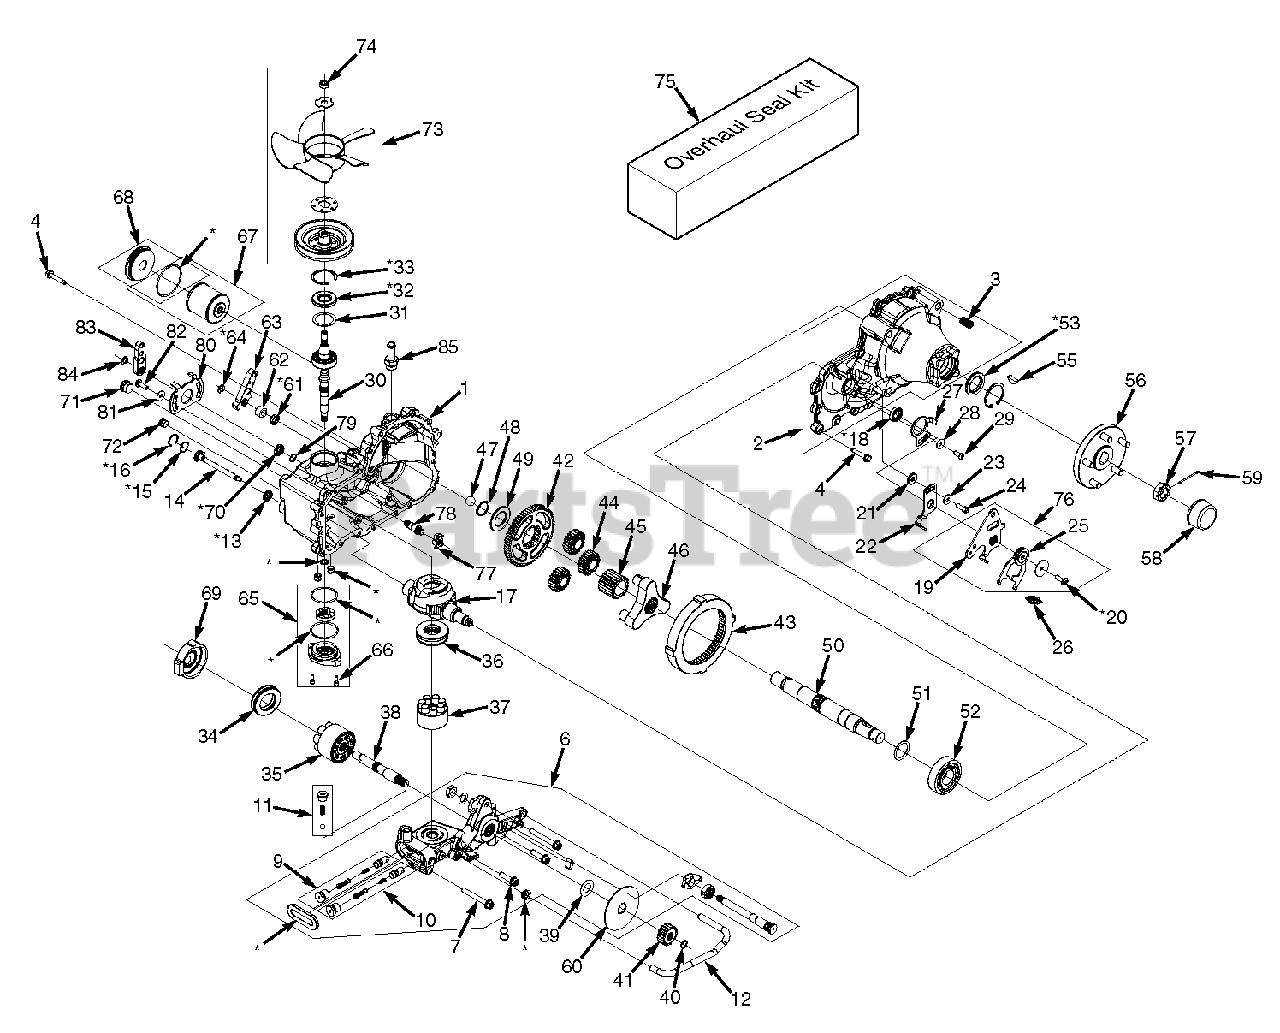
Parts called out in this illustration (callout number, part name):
1	Kit, Housing Main, LH
1	Kit, Housing Main, RH
2	Kit, Housing Side, LH
2	Kit, Housing Side, RH
3	Insert, 1/2-13 x 1-1/2" UNC
4	Screw, Hex Flange 5/16-18 x 1-1/2"
5	Tube, Sealant
6	Kit, Center Section, LH
6	Kit, Center Section, RH
7	Bolt, Hex Flange 3/8-16 x 3"
8	Screw, Hex Flange Head 3/8-16 x 1-1/2"
9	Kit, Shock Valve
10	Kit, Shock Valve
11	Kit, Charge Relief
12	Tube, Filter, LH
12	Tube, Filter, RH
13	Seal, Lip 12x 24 x 5 TC
14	Kit, Bypass Actuator
15	Spring, Wave
16	Ring, Retaining, HO-100
17	Swash Plate, 16cc. Machined
18	Seal, Lip 22 x 32 x 7
19	Arm, Control, LH
19	Arm, Control, RH
20	TWHCS, 5/16-18 x 1" (Patch)
21	Spacer, .320 x 1.005 x .179
22	Arm, Neutral, LH
22	Arm, Neutral, RH
23	Washer, .34 x .88 x .06
24	SHCS, 5/16-24 x .875 (Patch)
25	Assembly, RTN Uni-Directional (CCW) LH
25	Assembly, RTN Uni-Directional (CW) RH
26	Spring, Extension, RTN - 44lbs
27	Plate, Stop, LH
27	Plate, Stop, RH
28	Washer, .34 x .88 x .06
29	HBHCS, 5/16-18 x 3/4"
30	Kit, Input Shaft
31	Spacer
32	Seal, Lip 25 x 52 x 7 TC
33	Ring, Retaining Internal
34	Bearing, Thrust 42 x 68 x 16
35	Kit, Cylinder Block - 21cc.
36	Bearing, Thrust 35 x 70 x 22
37	Kit, Cylinder Block - 16cc.
38	Shaft, Motor
39	Washer, .89 x 1.50 x .04
40	Ring, Retaining
41	Gear, 19T
42	Gear, 65T
43	Gear, Ring 68T
44	Gear, Planet 23T
45	Gear, Sun 22T
46	Carrier
47	Ball, Thrust .75
48	Ring, Retaining 1-1/4"
49	Spacer, Thrust, Axle
50	Shaft, Axle
51	Washer, 1.40 x 1.75 x .05
52	Bearing, Ball 35 x 80 x 21
53	Seal, Lip 1.375 x 2.062 x .250
54	Ring, Retaining Internal
55	Key, Shaft, Axle
56	Kit, Hub, 5-Bolt
57	Nut, Hex 1-20 Slotted
58	Cap, Axle
59	Pin, Cotter 9/64 x 2"
60	Rotor, Brake
61	Seal, .56 x .88 x .19
62	Spacer, .57 x .86 x .53
63	Handle, Actuating
64	Ring, Retaining
65	Kit, Charge Cover
66	Screw, 1/4-20 x .625
67	Kit, Filter
68	Kit, Filter Plug
69	Plate, Motor Swash
70	Seal, 15 x 24 x 7
71	Plug, 7/8-14
72	Plug, 9/16-18
73	Kit, Fan/Pulley
74	Nut, Hex 1/2-20 w/Patch
75	Seal Kit
76	Kit, RTN Bi-Directional LH
76	Kit, RTN Bi-Directional RH
77	Cam, 2-Speed
78	Shaft, 2-Speed, Bevel
79	Ring, Retaining External .59"
80	Arm, Lock Down 2-Speed
81	Washer, .34 x .88 x .06
82	HBHCS, 5/16-18 x 3/4"
83	Handle, Actuating
84	Ring, Retaining External .375"
85	Fitting, 7/8-14 SAE, .625 Beaded
